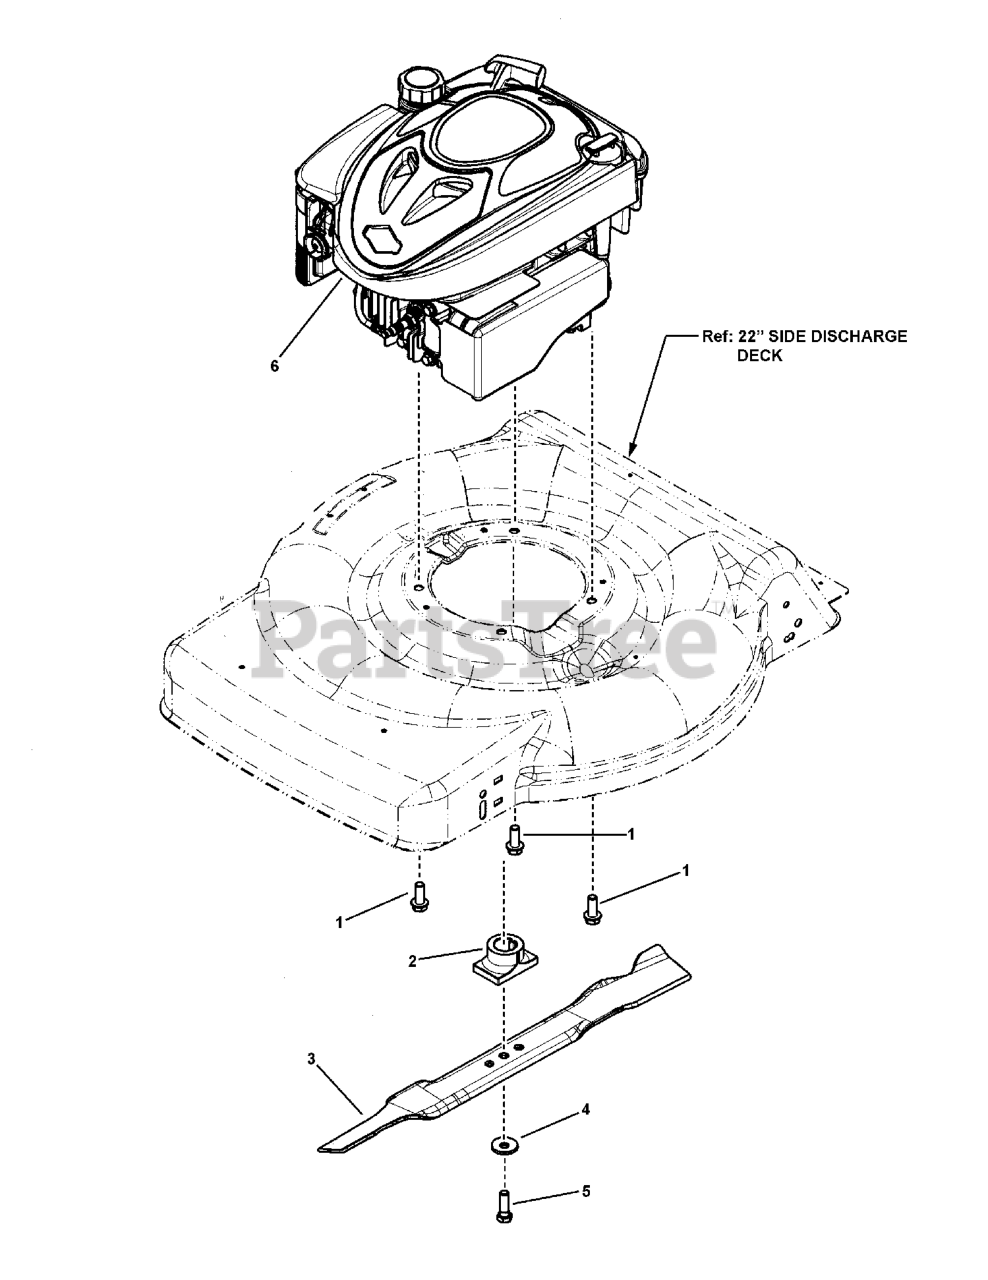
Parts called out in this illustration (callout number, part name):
1	SCREW, 3/8-16 x 1" Hex Washer Self-Tap
2	HUB, Blade, 22" Push
3	BLADE, 22", Walk Mower
4	WASHER, Belleville, .38" ID. x 1.183" OD.
5	SCREW, 3/8-24 x 1-1/4" Hex Head Cap, GR 5
6	* ENGINE, B&S, 650 Ser, X-Spec, B1, FC
6	* ENGINE, B&S, 675 Ser, X-Spec, B1, FC
